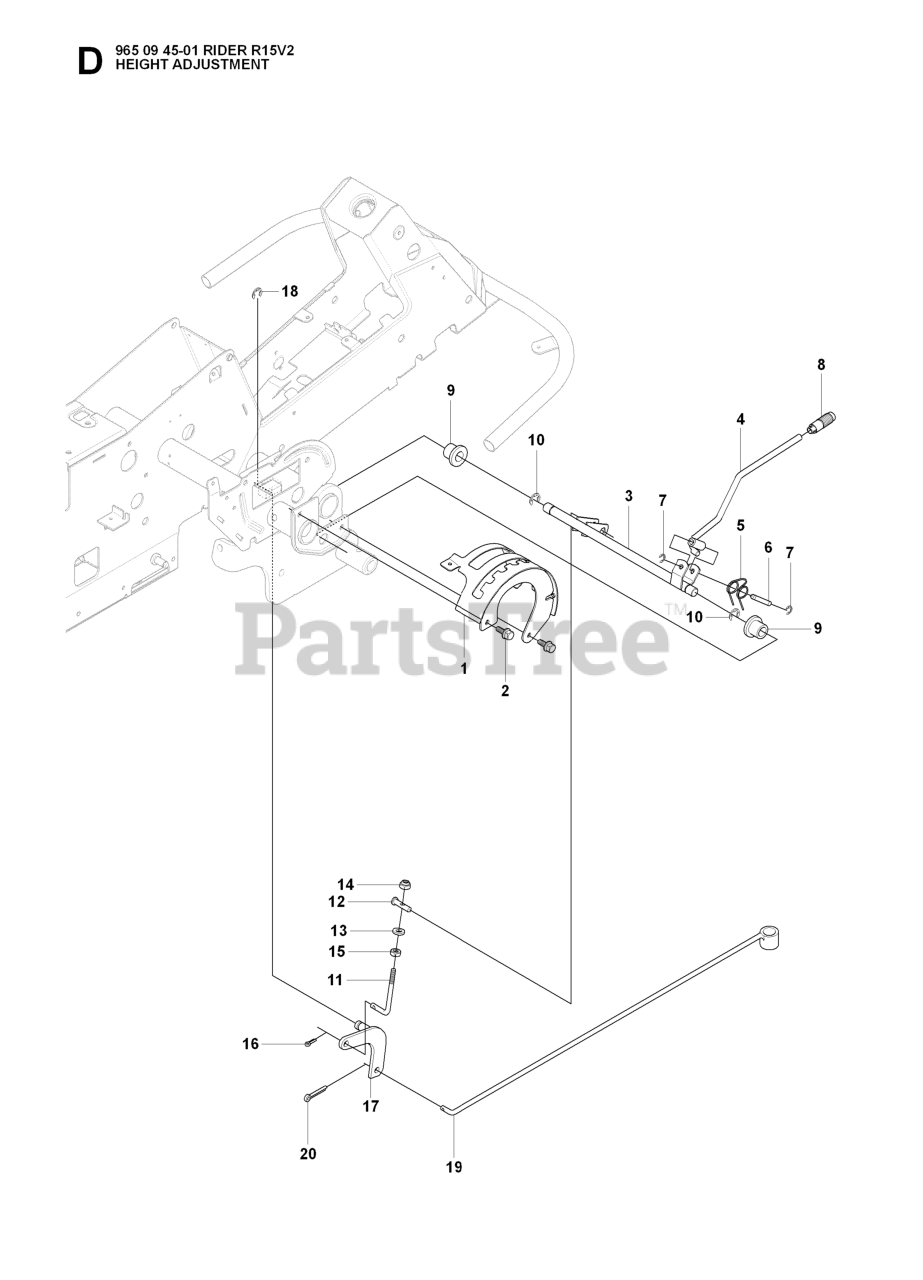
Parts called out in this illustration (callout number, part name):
1	CONTROL PLATE
3	HEIGHT ADJUSTER
4	HEIGHT ADJUSTER
5	HAIR PIN SPRING
8	GEAR STICK KNOB
9	BUSHING
13	WASHER
14	LOCKNUT M8
15	NUT
18	RETAINING RING
19	CLUTCH ROD
